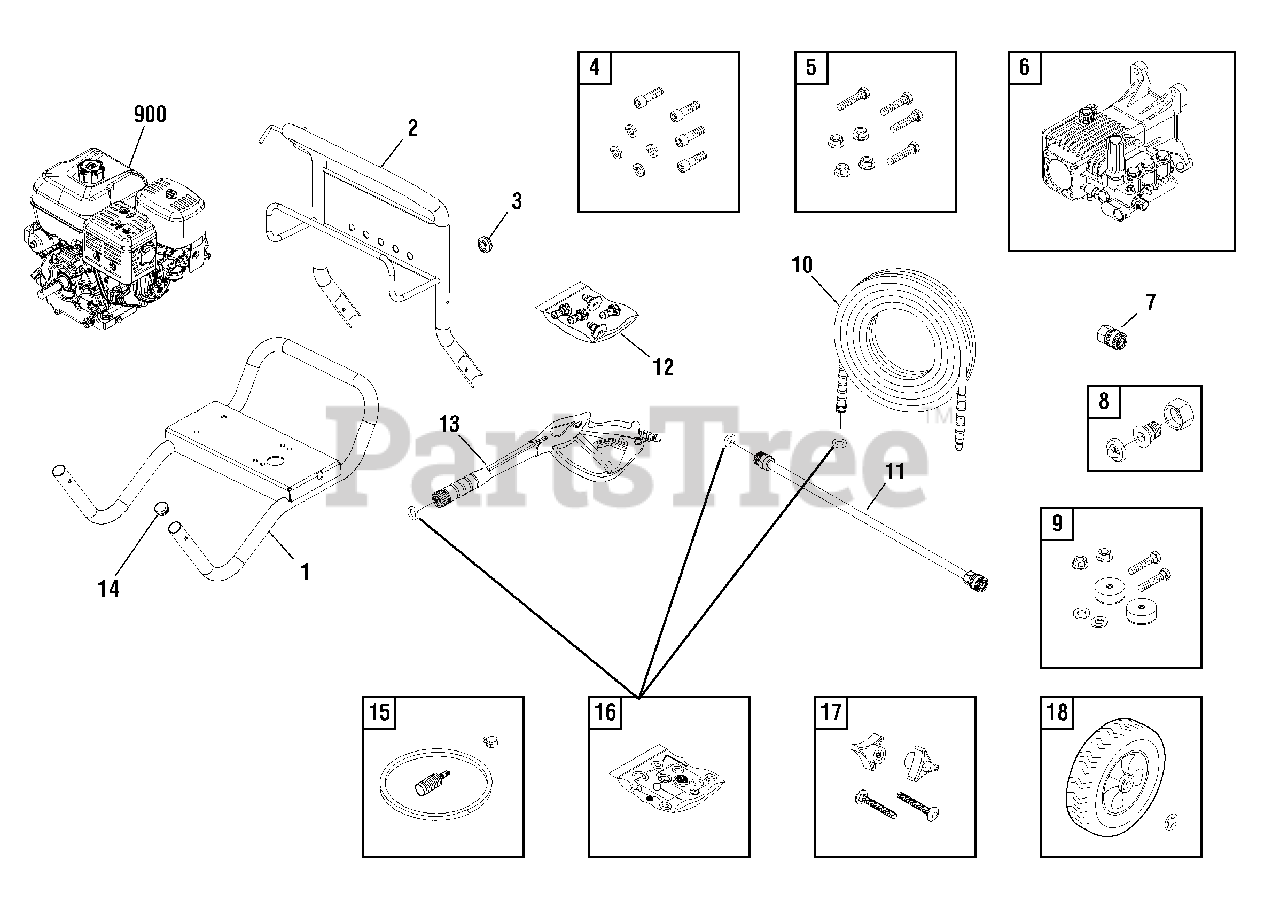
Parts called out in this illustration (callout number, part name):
4	KIT-HARDWARE, PUMP MOUNTING
5	KIT-HARDWARE, ENGINE MOUNTING
7	QUICK CONNECT
8	ADAPTER-GARDEN HOSE
9	MOUNT-VIBRATION
10	HOSE
11	EXTENSION, QC
17	KIT-HARDWARE, HANDLE
900	** ENGINE
